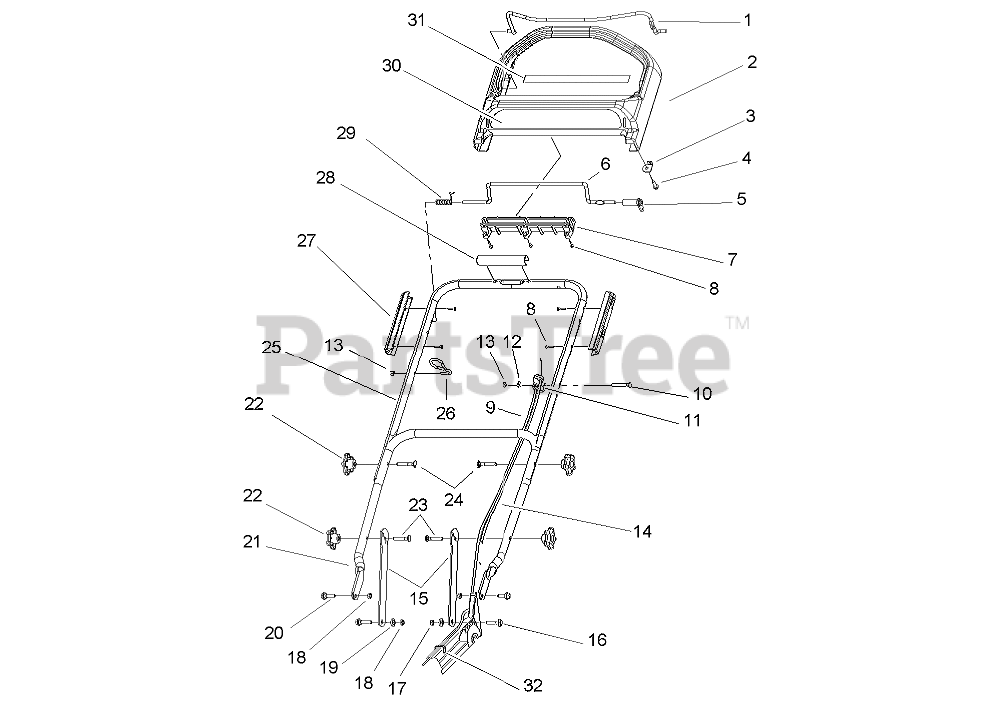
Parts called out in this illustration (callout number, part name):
1	BAIL-BRAKE
2	HANDLE-CONTROL
3	Retainer-Cable
4	SCREW
5	LEVER-TRACTION
6	BAR-CONTROL, TRACTION
7	RETAINER-CONTROL ROD, TRACTION
8	SCREW-PPH
9	CABLE-BRAKE
10	SCREW
11	ANCHOR-CABLE
12	WASHER-FLAT
13	NUT-LOCK, NI
14	Cable-Traction
15	LATCH-HANDLE
16	SCREW-SHOULDER
17	NUT-LOCK, NI
18	NUT-LOCK, NI
19	SPACER
20	SCREW-SHOULDER
21	HANDLE-LOWER
22	KNOB-HANDLE
23	SCREW-CARR
24	SCREW-HANDLE
25	HANDLE-UPPER
26	GUIDE-ROPE
27	GUIDE-HANDLE, CONTROL
28	COVER-HANDLE
29	SPRING-TORSION, RH
30	DECAL-PANEL
31	DECAL-PANEL, REAR
32	TIE-CABLE
